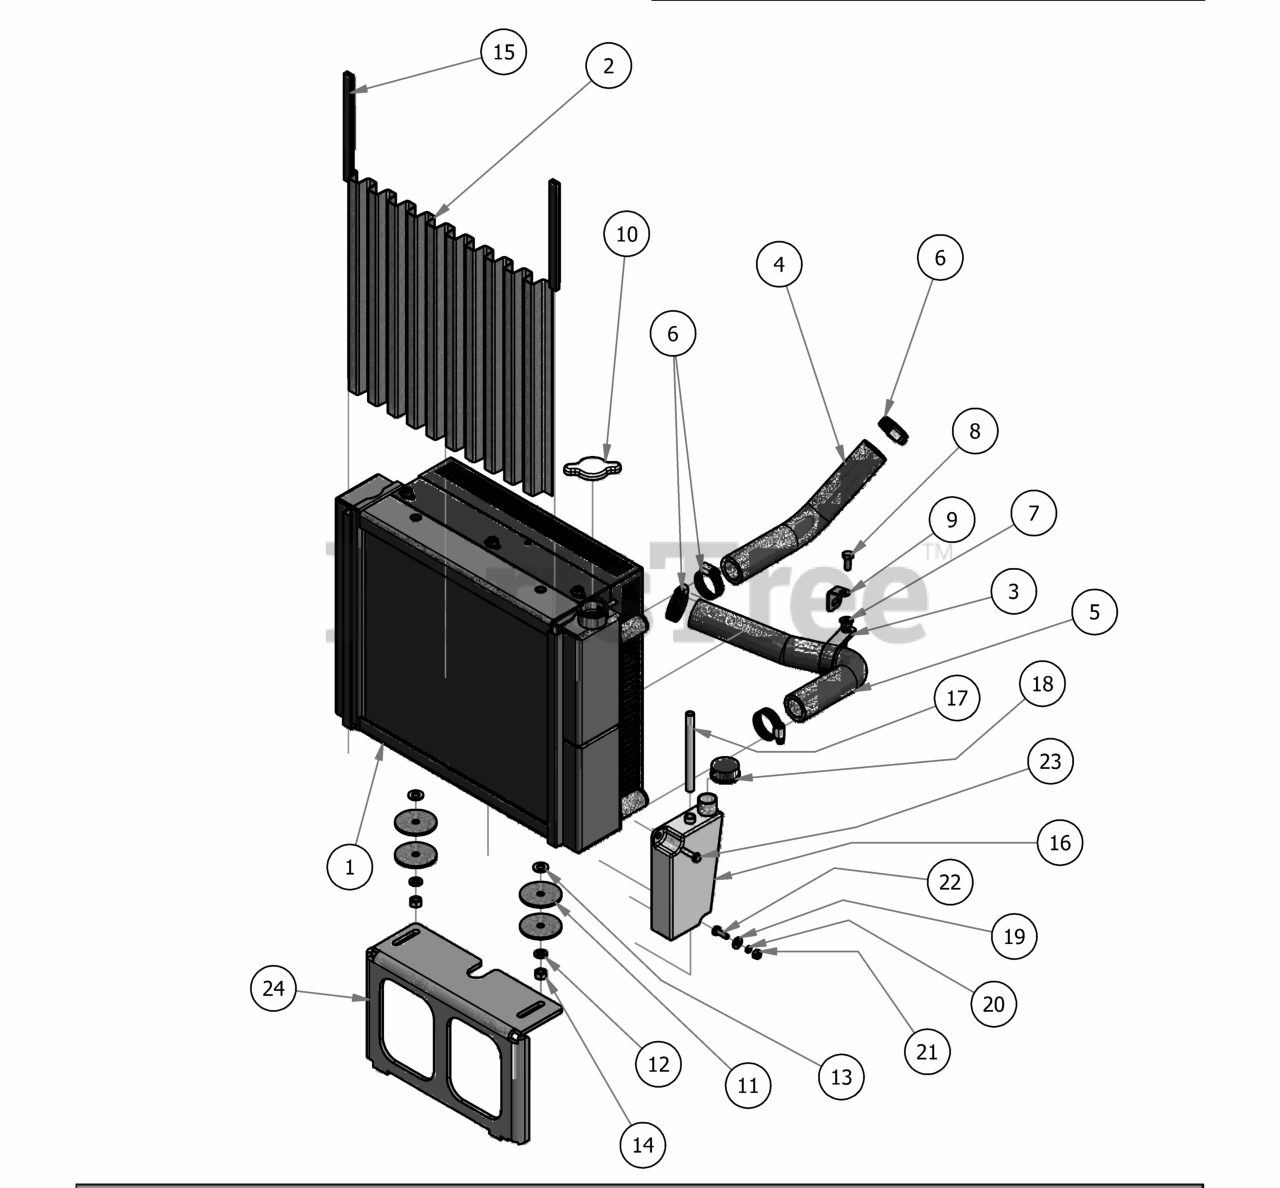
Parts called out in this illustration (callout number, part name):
1	Radiator- Diesel
2	Radiator Screen-Diesel
3	Diesel Clamp 1 3/4" Vinyl
4	Top Radiator Hose for Diesel
5	Bottom Radiator Hose for Diesel
6	1 1/8" Hose Clamp
7	5/16" Nylon Flange Nut
8	5/16" x 1" Hex Bolt
9	Diesel Radiator Hose Clamp Bracket
10	Radiator cap
11	3/8 x 2-1/4 OD Fibre Washer
12	3/8" Lock Washer
13	3/8" Flat Washer
14	3/8" Hex Nut
15	Rubber Trim
16	overflow Reservoir- 28/35Hp Diesel
17	5/16 Clear Hose
18	Reservoir Tank Cap-Overflow
19	1/4" Flat Washer
20	1/4" Lock Washer
21	1/4" Hex Nut
22	1/4" x 3/4" Hex Bolt
23	1/4 x 1 Hex Head tek screw
24	Bolt On Radiator Support
